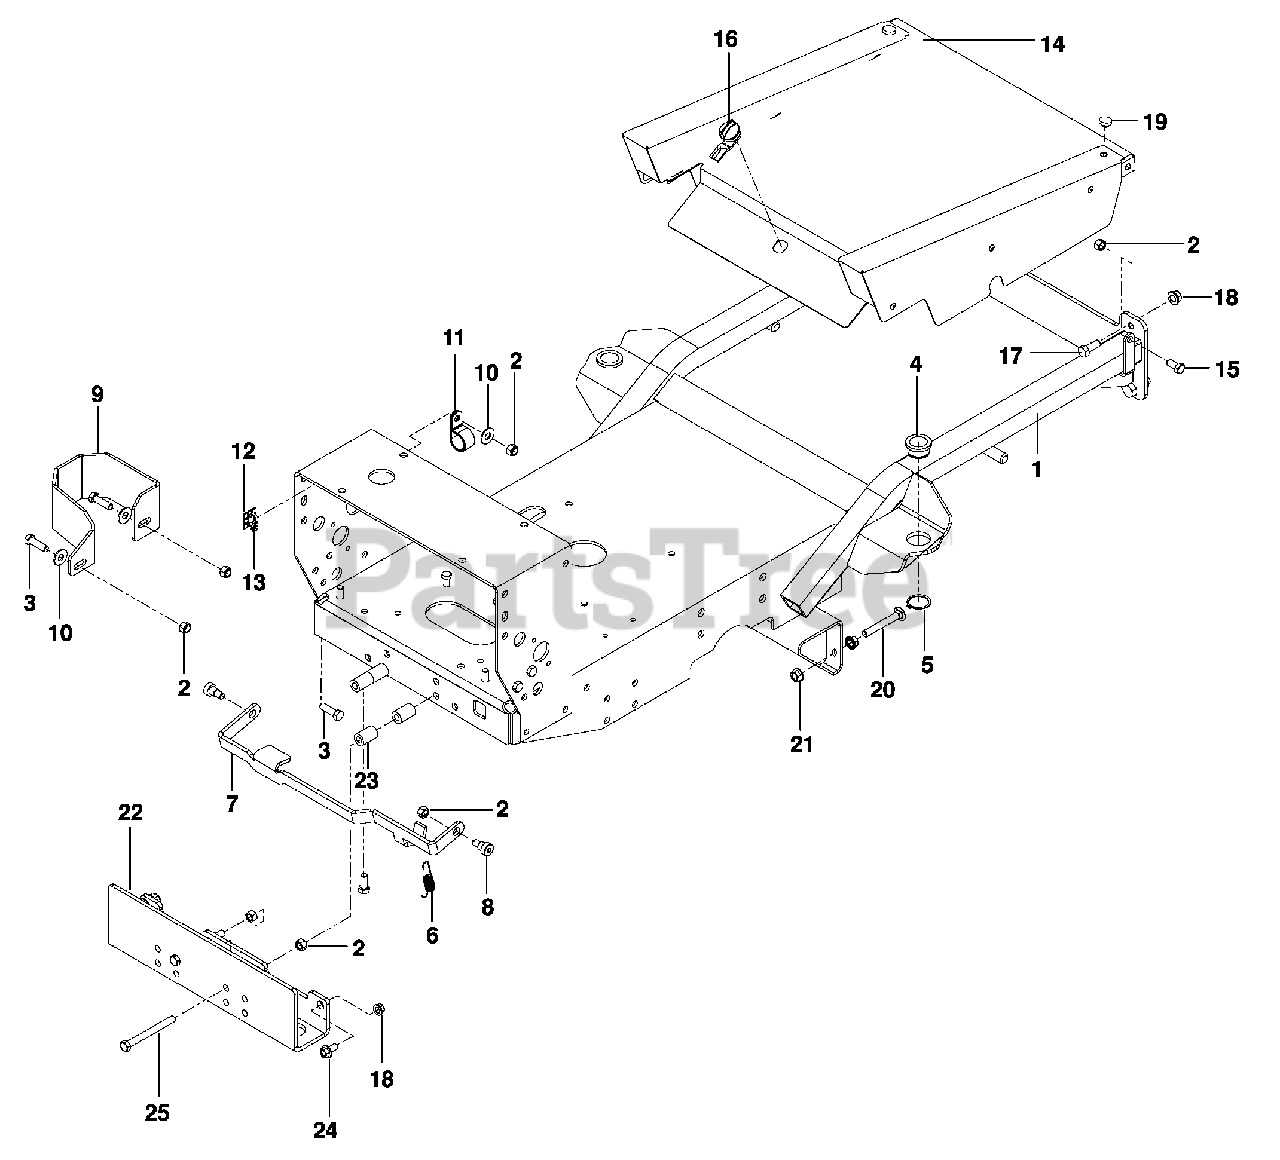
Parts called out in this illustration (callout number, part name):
2	NUT 3/8-16 HEX NYLOC
3	HCS 3/8-16 x 1¼
4	BUSHING, HOC
5	RING, SNAP
6	SPRING, EXTENSION
7	BAR, THROW OUT
8	SB 3/8-16 x 3/8 SKT HD
9	GUARD, FILTER
10	WASHER 3/8 FLAT
12	MOUNTING BLOCK
14	COVER, CENTER
15	HCS 3/8-16 x ¾
16	LATCH, SHORT WING
17	HCS ½-13 x 1¼
18	NUT ½ HEX FLG NYLOC
20	RHSNB 3/8-16 x 2¾
21	NUT 3/8-16 HEX WHIZLK
24	HFFS ½ -13 x 1
25	HCS 3/8-16 X 3¾
26	HCS 3/8-16 x 3¾
28	HFFS ½-13 x 1
